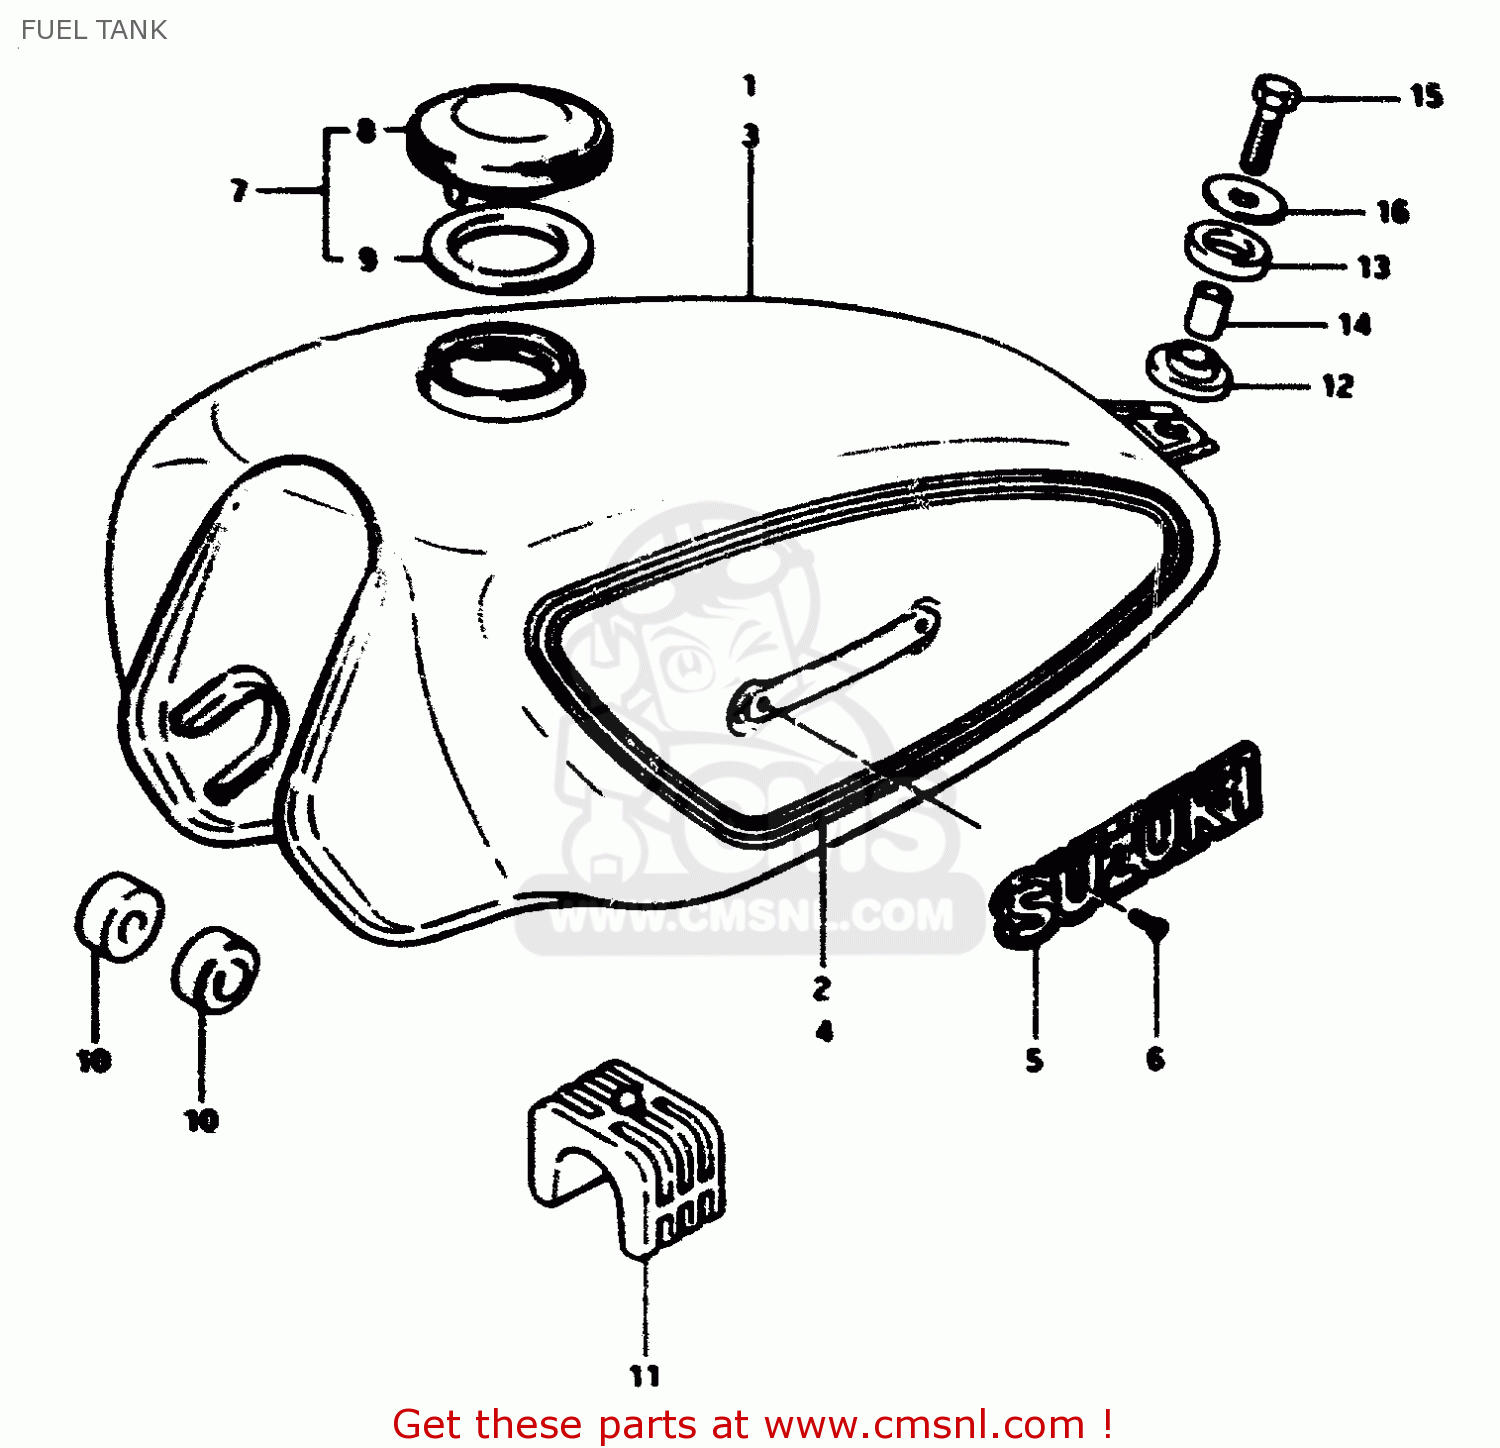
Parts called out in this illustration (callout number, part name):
1	TANK, FUEL (YELLOW)
2	TAPE SET
3	TANK, FUEL (RED)
4	TAPE SET
5	EMBLEM
6	SCREW 3X6
7	CAP ASSY,FUEL TANK FILLER
8	CAP,FUEL TANK
9	GASKET (NAS)
10	CUSHION
11	CUSHION, CENTER
12	CUSHION
13	CUSHION
14	SPACER(8.5X12X19)
15	BOLT (8X30)
16	WASHER (8.5X29X1.6)
